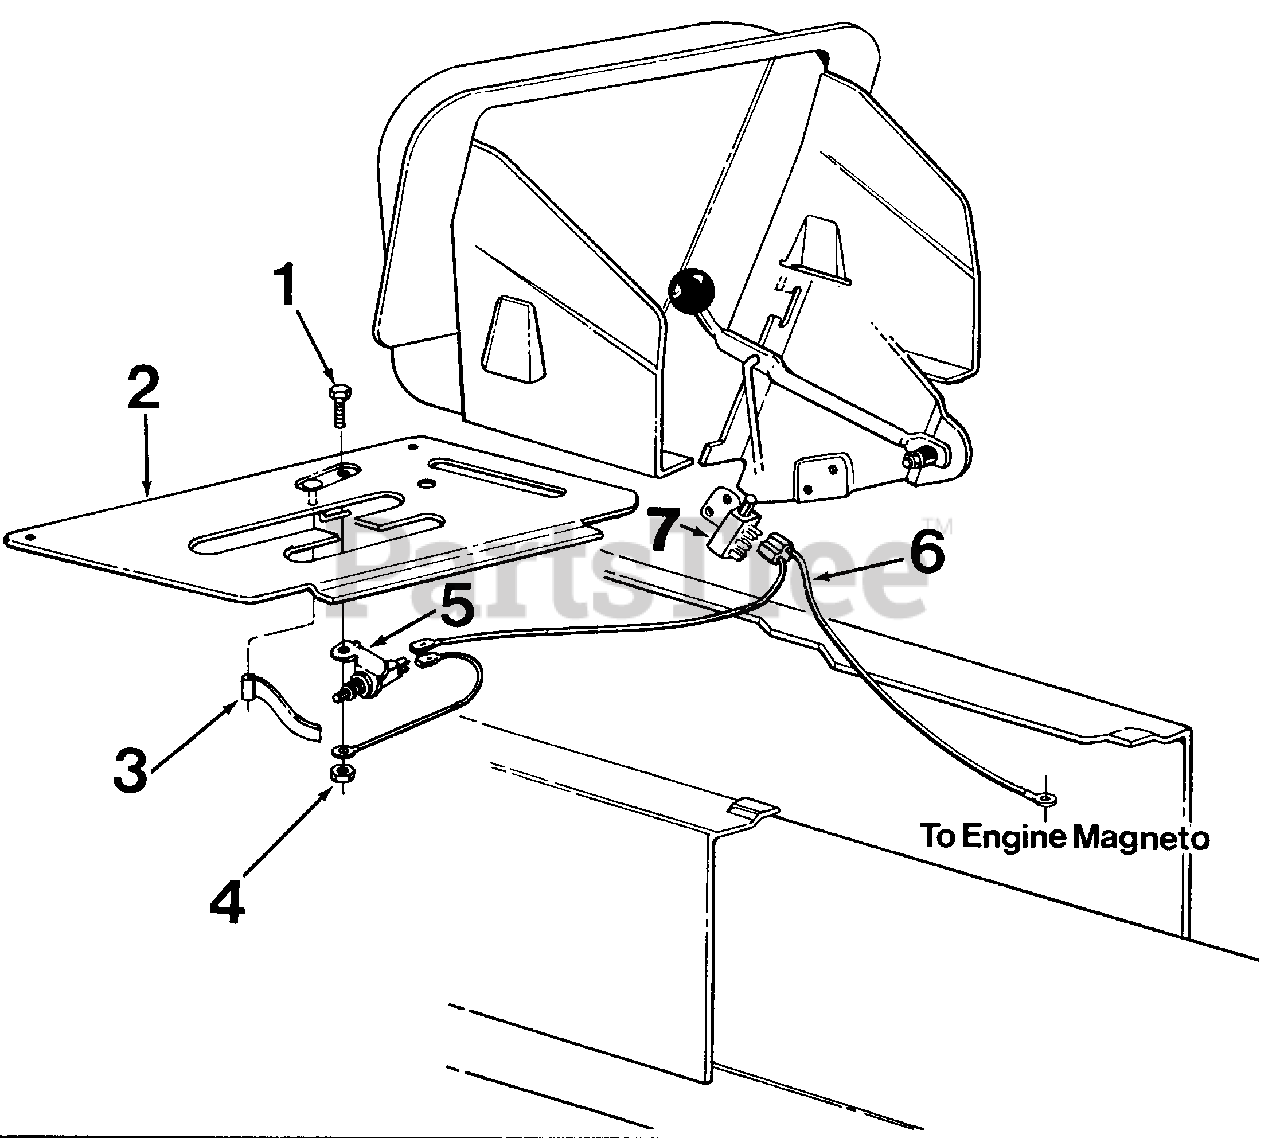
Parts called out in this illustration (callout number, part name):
1	Hex Bolt1/4-20 x .50" Lg.
2	Transmission Cover Ass'y.
3	Switch Actuator Spring Lever
4	Hex Nut 1/4-20 Thd.
5	Safety Switch
6	Reverse Lockout Wire Harness
7	Safety Switch
